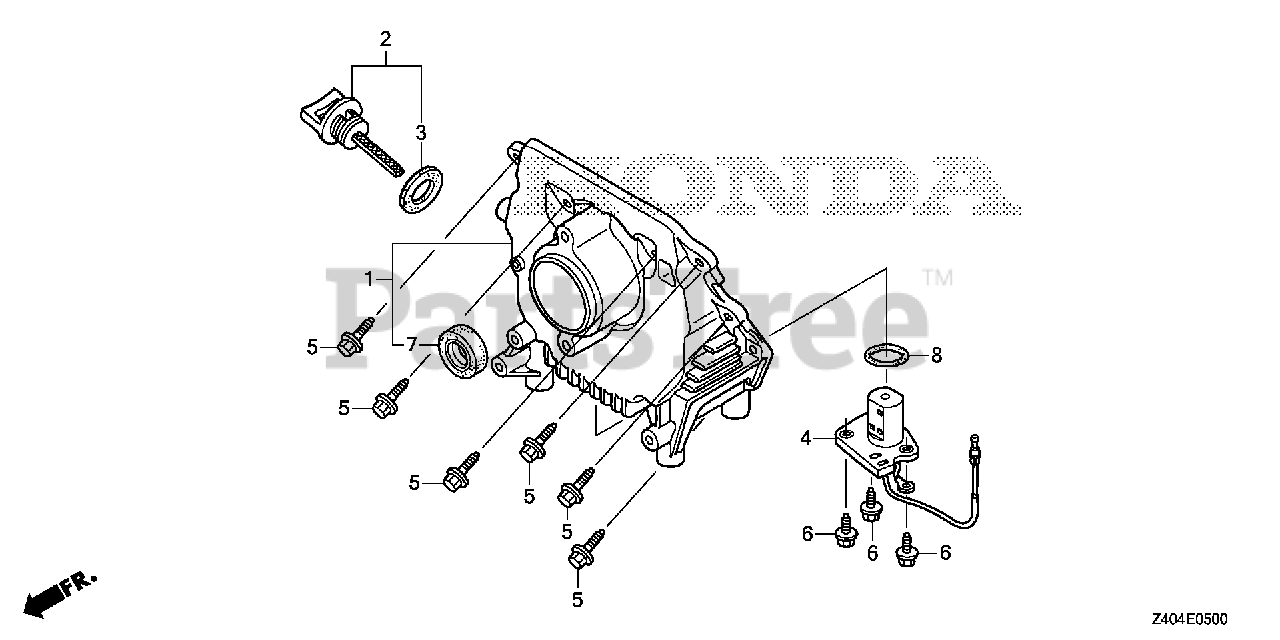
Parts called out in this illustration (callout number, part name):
1	CASE ASSY., OIL
2	CAP ASSY., OIL FILLER
3	GASKET, OIL FILLER CAP
4	SWITCH ASSY., OIL LEVEL
5	BOLT, FLANGE (5X23)
6	BOLT, FLANGE (5X14)
7	OIL SEAL (17X27X5) (KOYO)
8	O-RING (34.6X2.5)
